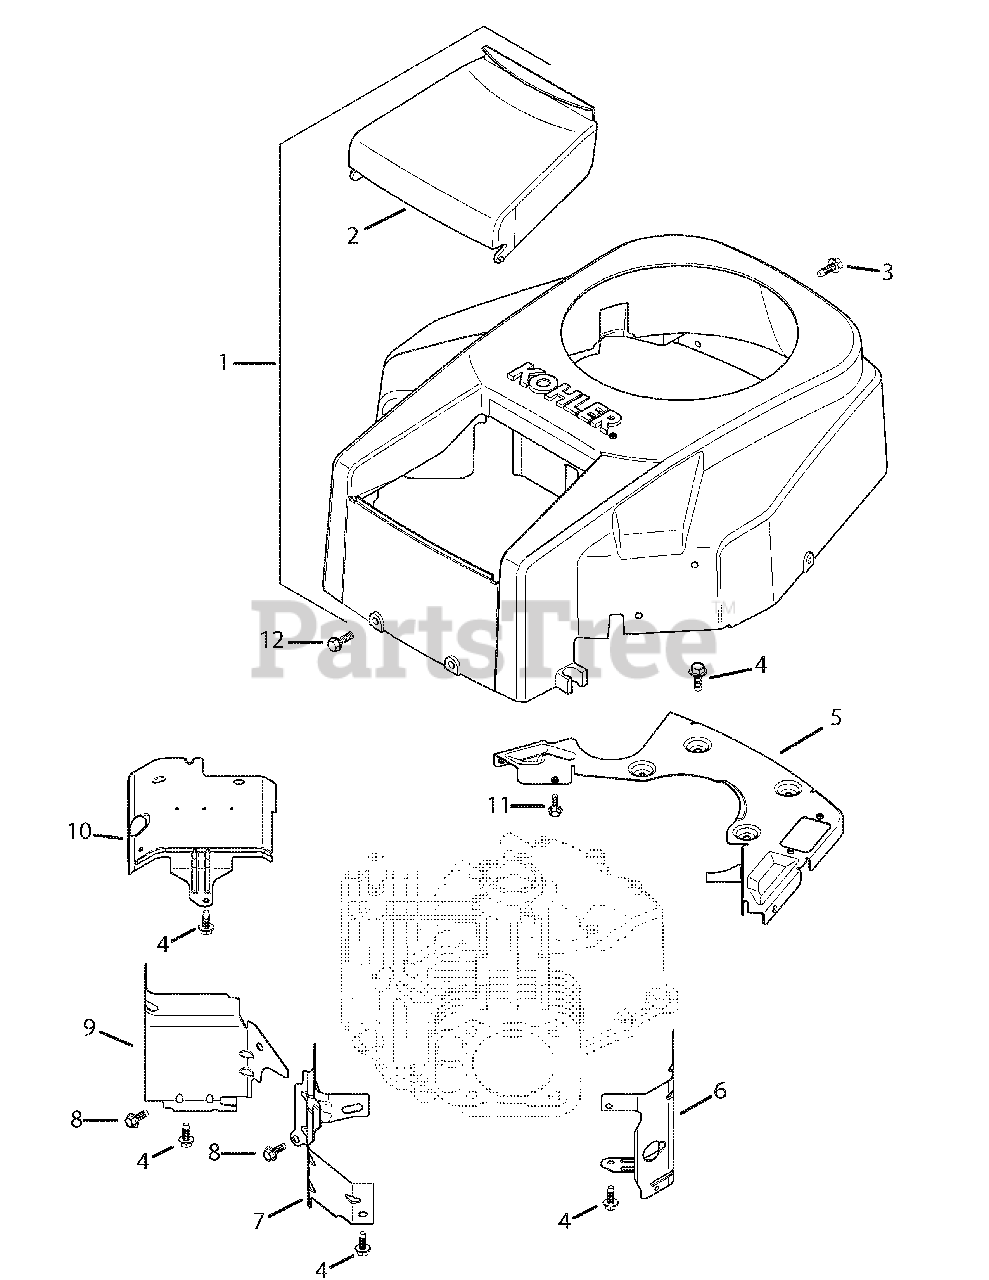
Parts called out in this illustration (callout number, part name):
1	Housing, blower
2	Cover, air cleaner
3	Screw, hex. flange M5x0.8x16
4	Screw, hex. flange M6x1.0x16
5	Plate, backing w/rectifier-regulator opening
6	Baffle, cylinder barrel - #2 side
7	Baffle, valley - #2 side
8	Screw, hex. flange M5x0.8x10
9	Baffle, valley - #1 side
10	Baffle, cylinder barrel-#1 side
11	Screw, hex. flange M5x0.8x20
12	Screw, hex. cap M6x1.7x18
